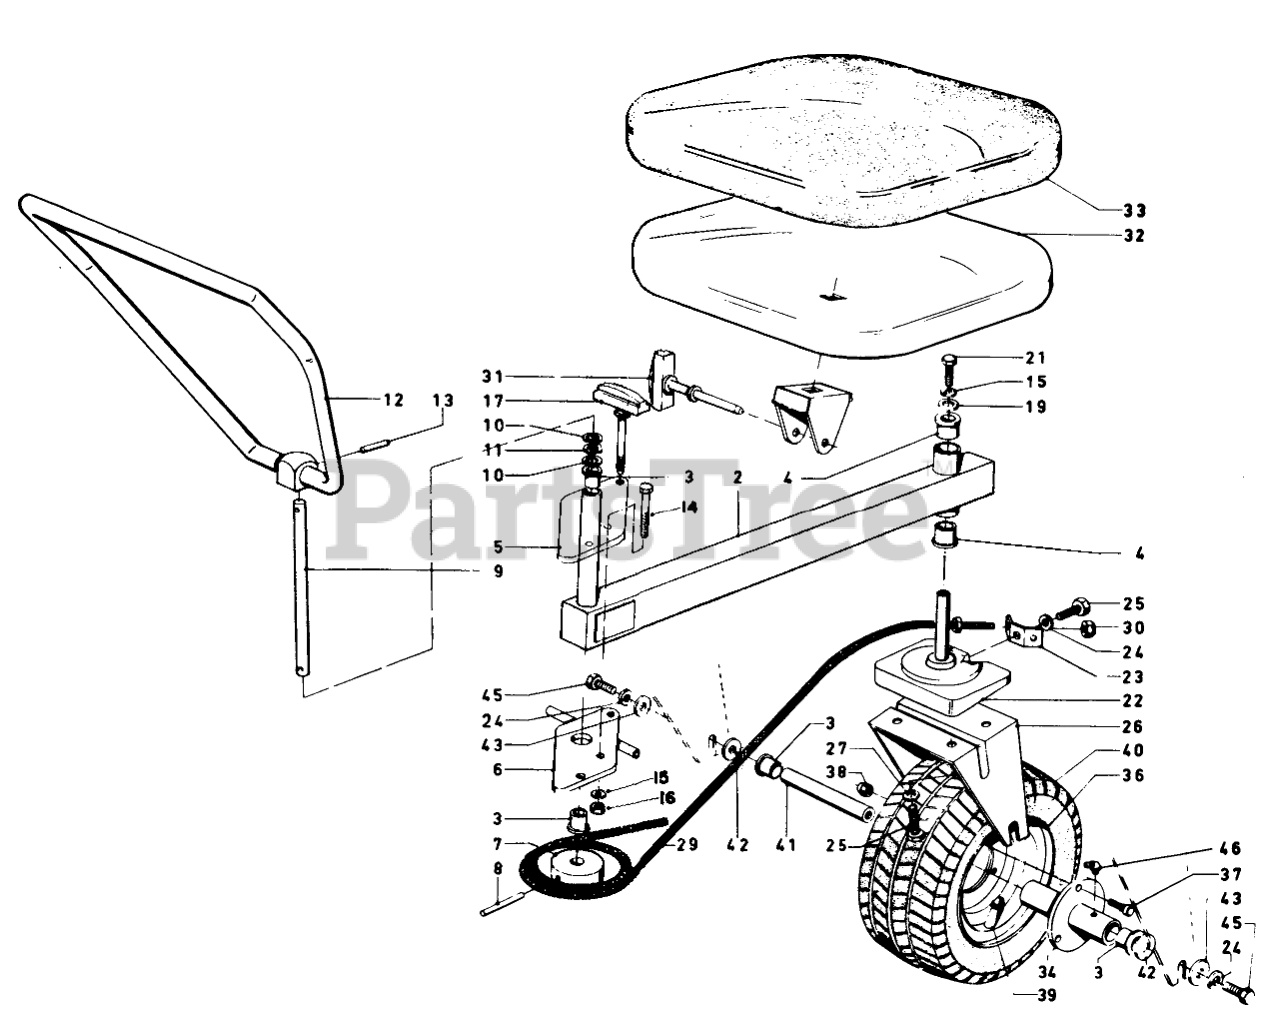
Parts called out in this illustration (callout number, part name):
2	Rear Frame (Incl. Ref. # 3 & 4)
3	3/4IDX1LG FLANGE BSHG
4	FLANGE BUSHING
5	Plate, Upper Hinge
6	Plate, Lower Hinge
7	FRT STRG PULLEY RO
9	STEERING SHAFT
10	WASHER-THRUST
11	3/4 SPRING WASHER
12	STEERING HANDLE ASM
13	PIN-ROLL, SLOTTED
14	SCREW-HH
15	WASHER-LOCK
16	NUT-HEX
17	STUD & HANDLE ASM
19	WASHER
21	SCREW-HH
22	PVT CSTR/SFT WARO
23	CABLE BRACKET R
24	WASHER-LOCK
25	SCREW-HH
26	Wheel Fork
27	WASHER-LOCK
29	STRG SWAGED CABLE ASM
30	NUT-LOCK
31	Handle Assembly
32	Seat Assembly
33	SEAT PAD
34	Hub (Incl. Ref. # 3)
36	Wheel Disc Assy.
37	DRIVE STUD
38	LUG NUT
39	STEM-VALVE
40	Tire
41	Shaft
42	THRUST WASHER
43	WASHER-FLAT
45	SCREW-HH
46	FITTING-LUBE, 45 DEG
